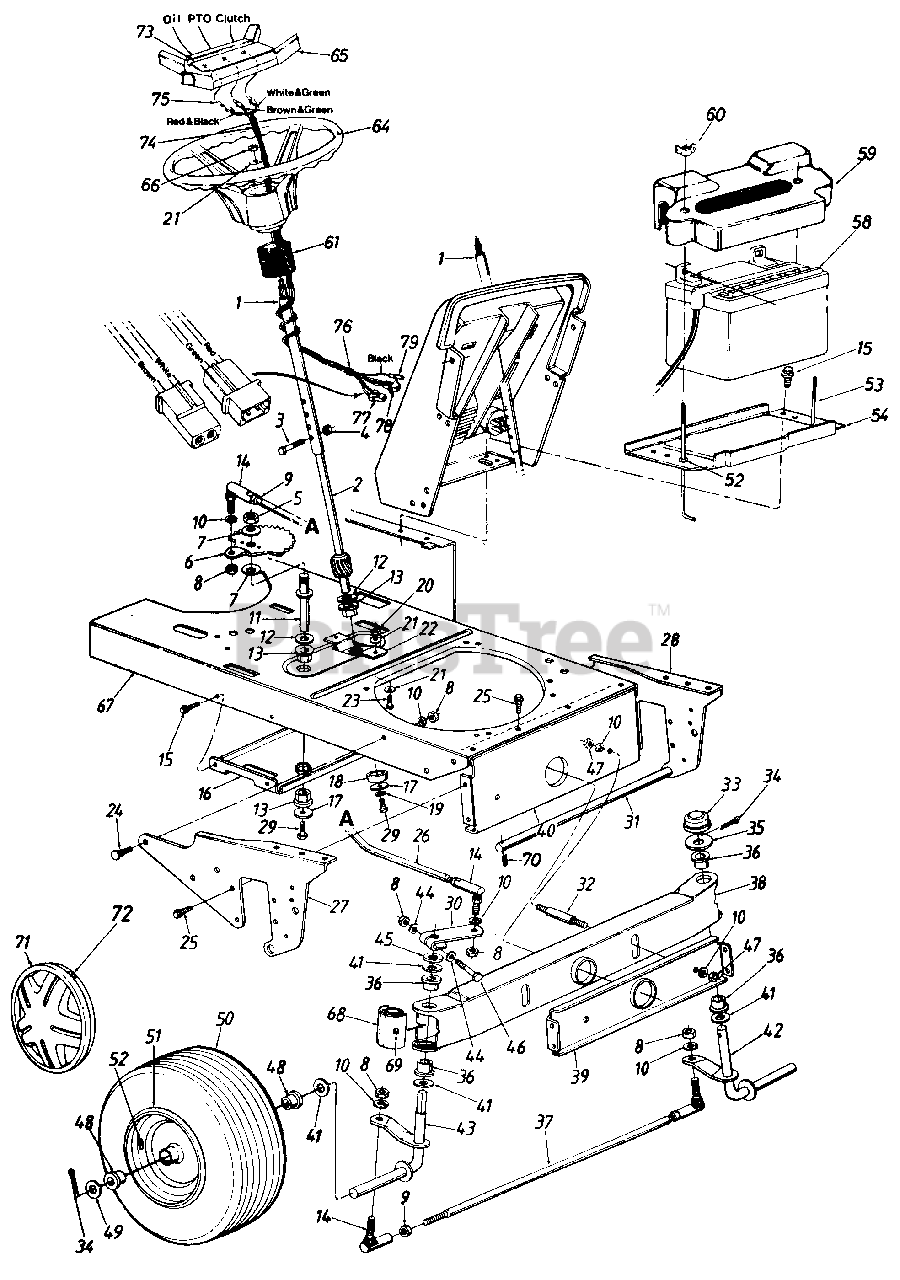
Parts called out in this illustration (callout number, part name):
1	Steering Column Ass'y.
2	Lower Steering Shaft
3	Hex Bolt 1/4-20 x 1.31" Lg.
4	Hex L-Nut 1/4-20 Thd.
5	Hex Nut 5/8-18 Thd.
6	Steering Gear Segment
7	Bell-Wash. 5/8" I.D. x 1.25" O.D.
8	Hex Nut 3/8-24 Thd.
9	Hex Jam Nut 3/8-24 Thd.
10	L-Wash. 3/8" I.D.
11	Steering Gear Segment Shaft
12	Fl-Wash. .64" I.D. x 1.24" O.D.
13	Hex Flange Brg. .63" I.D.
14	Ball Joint Ass'y.
15	Hex Wash. Hd. TT-Tap Scr. 1/4-20 x .5" Lg.
16	Deck Idler Support Brkt.
17	Fl-Wash. .33" I.D. x 1.25" O.D.
18	Spacer .985" I.D. x 1.25" O.D.
19	L-Wash. 5/16" I.D.
20	Hex Nut 5/16-24 Thd.
21	Bell-Wash. .345" I.D. x .88" O.D.
24	Ribbed Neck Bolt 3/8-24 x .8" Lg.
25	Hex Wash. TT-Tap Scr. 5/16-18 x .62" Lg.
26	Steering Drag Link
27	Pivot Bar Side Plate R.H.
28	Pivot Bar Side Plate L.H.
29	Hex Bolt 5/16-18 x .62" Lg.
30	Steering Arm
31	Deck Connecting Rod
32	Pivot Bar Shld. Bolt 3/8-16 x 5/8" Lg.
33	Cap
34	Cotter Pin 5/32" Dia.
35	Flat Washer
36	Flange Brg. .757" I.D.
37	Tie Rod 20.25" Lg.
38	Pivot Bar Assy.
41	Fl-Wash. .76" I.D. x 1.49" O.D.
42	Front Axle Ass'y. L.H.
43	Front Axle Ass'y. R.H.
44	Bowed Washer
45	Spacer .755" I.D. x 1.25" O.D.
46	Hex Bolt 3/8-24 x 2.25" Lg.
47	Hex Nut 3/8-16 Thd.
48	Bronze Flange Brg. .75" I.D.
49	Fl-Wash. .71" I.D. x 1.5" O.D.
50	Wheel Ass'y. Comp.
51	Rim Only
52	Push Nut
53	Battery Hold Down Rod
54	Battery Plate
58	Battery (275 Cold Crank Amps)
59	Battery Cover
60	Wing Nut Plastic 1/4-20 Thd.
61	Steering Bellow
64	Steering Wheel
65	Steering Wheel Insert
66	Hex L-Nut 5/16-24 Thd.
67	Lower Frame
68	Pivot Bar End Cap
69	Grease Fitting
70	Internal Cotter Pin
71	Hub Cap
72	Spring Clip
73	Steering Wheel Insert Label
74	Wire Harness
75	Bulb
76	Clamp
77	Connector
78	Connector
79	Connector
